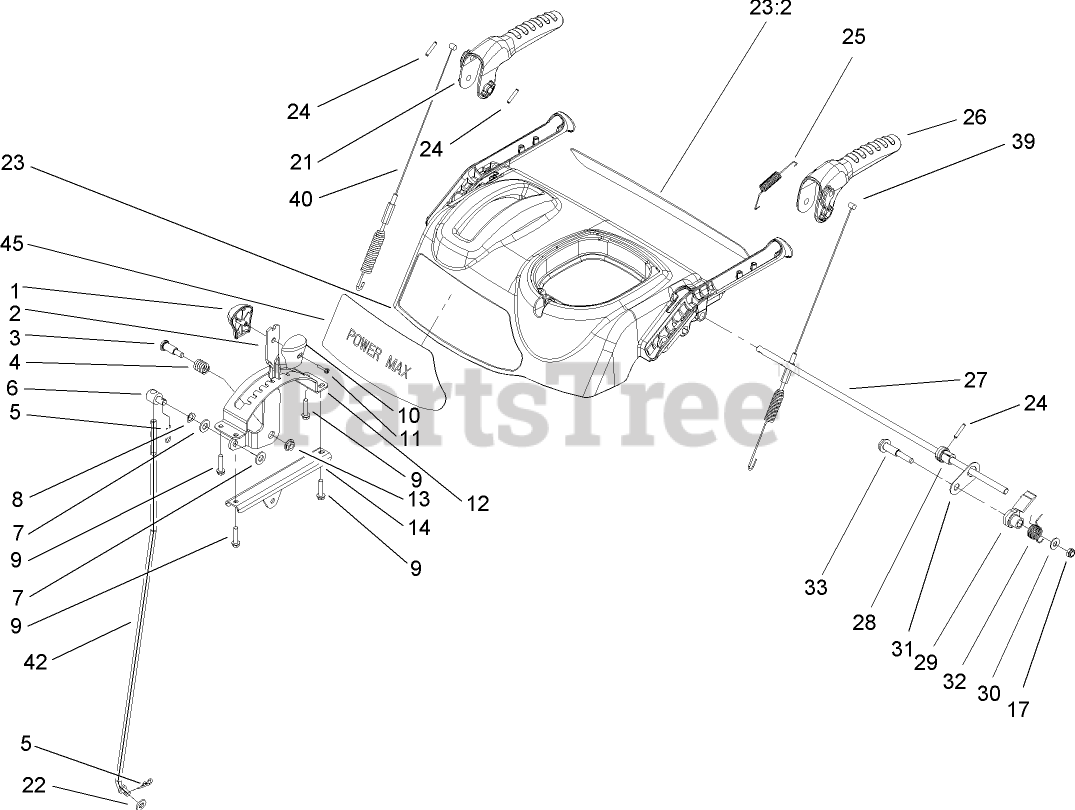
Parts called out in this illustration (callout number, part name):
1	KNOB-SHIFT, RH
2	SELECTOR-SPEED
3	SCREW-SHOULDER
4	SPRING-COMPRESSION
6	TRUNNION
7	WASHER-FLAT
8	WASHER-SPRING
9	SCREW-PLASTITE
10	KNOB-SHIFT, LH
11	SCREW-PPH
12	GUIDE-SELECTOR, SPEED
13	NUT-HF
14	MOUNT-SELECTOR, SPEED
17	NUT-LOCK, NI
21	LEVER-AUGER
22	WASHER-FLAT
23	CONTROL PANEL ASM
23:2	DECAL-PANEL, BACK CONTROL
24	PIN-SPRING
25	SPRING-TENSION
26	LEVER-TRACTION
27	ROD-LOCKOUT
28	CAM-LOCKOUT
29	LATCH-LOCKOUT
30	WASHER-FLAT
31	LINK-LOCKOUT
32	SPRING-TORSION
